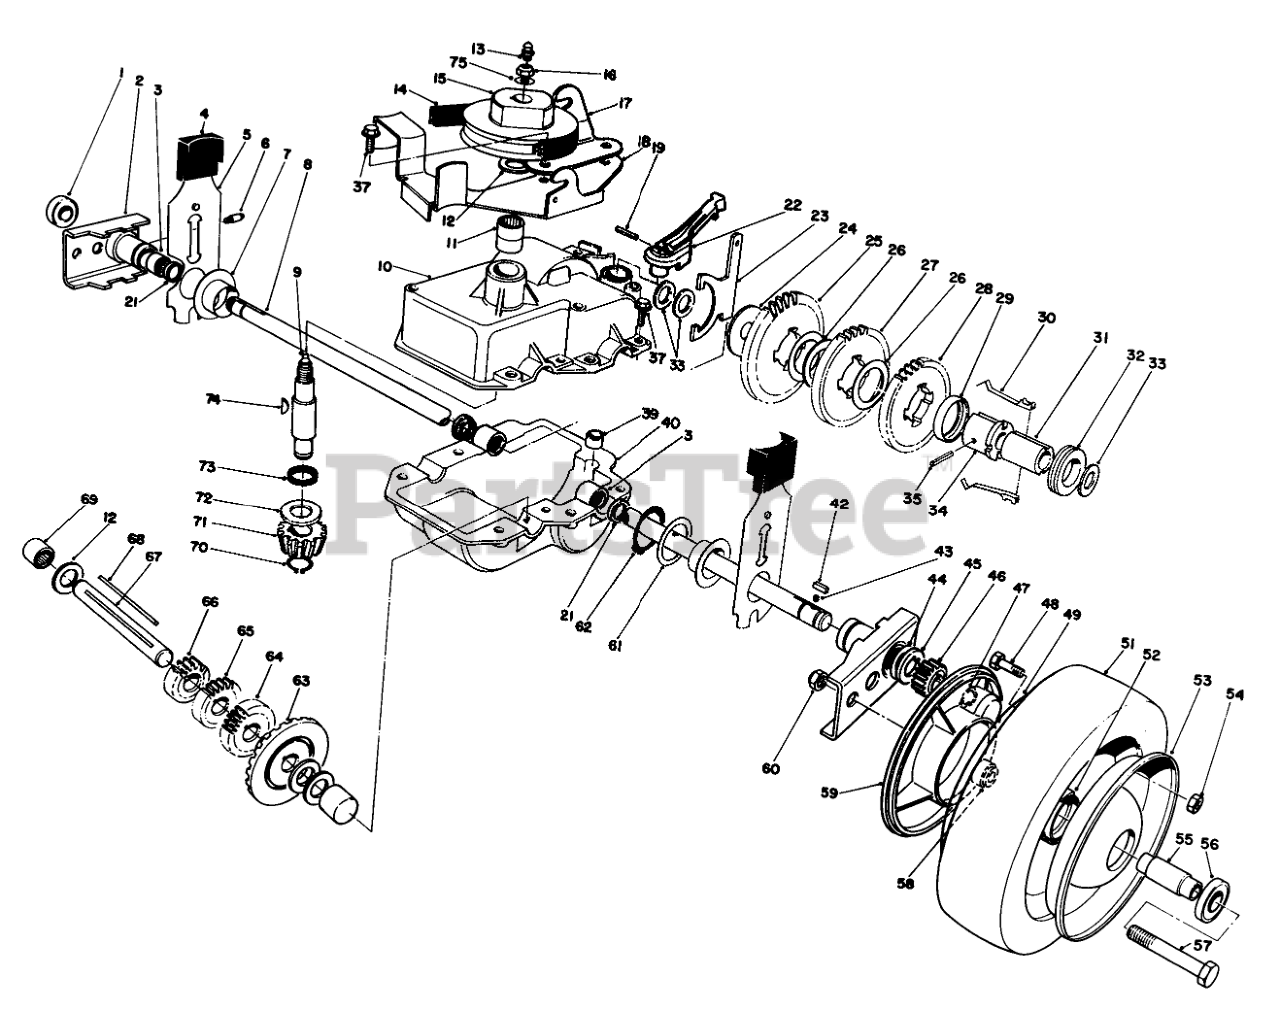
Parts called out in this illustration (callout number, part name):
1	BEARING-WHEEL
2	Pivot Arm Assembly (Incl. Ref. #1, 3, 6 & 21)
3	BEARING-ROLLER
4	KNOB-ARM
5	REAR SPRING ARM ASM
6	FITTING-GREASE
7	CAP-END
8	SHAFT-OUTPUT
9	Shaft-Input (Incl. Ref. #13)
10	Upper Case Assembly (Incl. Ref. #11 & 73)
11	BEARING-NEEDLE
12	WASHER-THRUST
13	FITTING-GREASE, ZERK
14	V-BELT
15	PULLEY
16	NUT-HEX
17	Bracket-Traction Engage
18	Belt Guide Bracket
19	PIN-COIL
21	SEAL-OIL
22	LEVER-SHIFT
23	YOKE-SHIFT
24	WASHER
26	WASHER
27	GEAR-42T
28	GEAR-38T
29	RETAINER-KEY
30	KEY-SHIFT
31	SLEEVE
32	COLLAR-SHIFT
33	WASHER-PLAIN
34	SLEEVE-GEAR
35	PIN-GROOVE
37	SCREW-HWHTF
39	BUSHING-YOKE
40	CASE-GEAR, LOWER
42	KEY RECTANGULAR
43	SPRING-COMPRESSION
44	WASHER-THRUST, OUTER
45	WASHER-THRUST, OUTER
46	GEAR-PINION
47	RING-RETAINING
48	SCREW-HH
49	Wheel-Half
52	HUB-BEARING
53	Wheel-Half
54	NUT-LOCK, NI
55	SPACER-BEARING
56	BEARING-WHEEL
57	SCREW-HH
58	SPACER-COVER, WHEEL
59	COVER-WHEEL
60	NUT-LOCK, CONE
61	WASHER
62	RING-RETAINING
63	GEAR-BEVEL
64	GEAR-18T
65	GEAR-14T
66	GEAR-12T
67	SHAFT-INTERMEDIATE
69	BEARING-NEEDLE, CLOSED
70	RING-RETAINING
71	PINION-BEVEL
72	WASHER-THRUST
74	KEY-WOODRUFF
75	WASHER-FLAT
